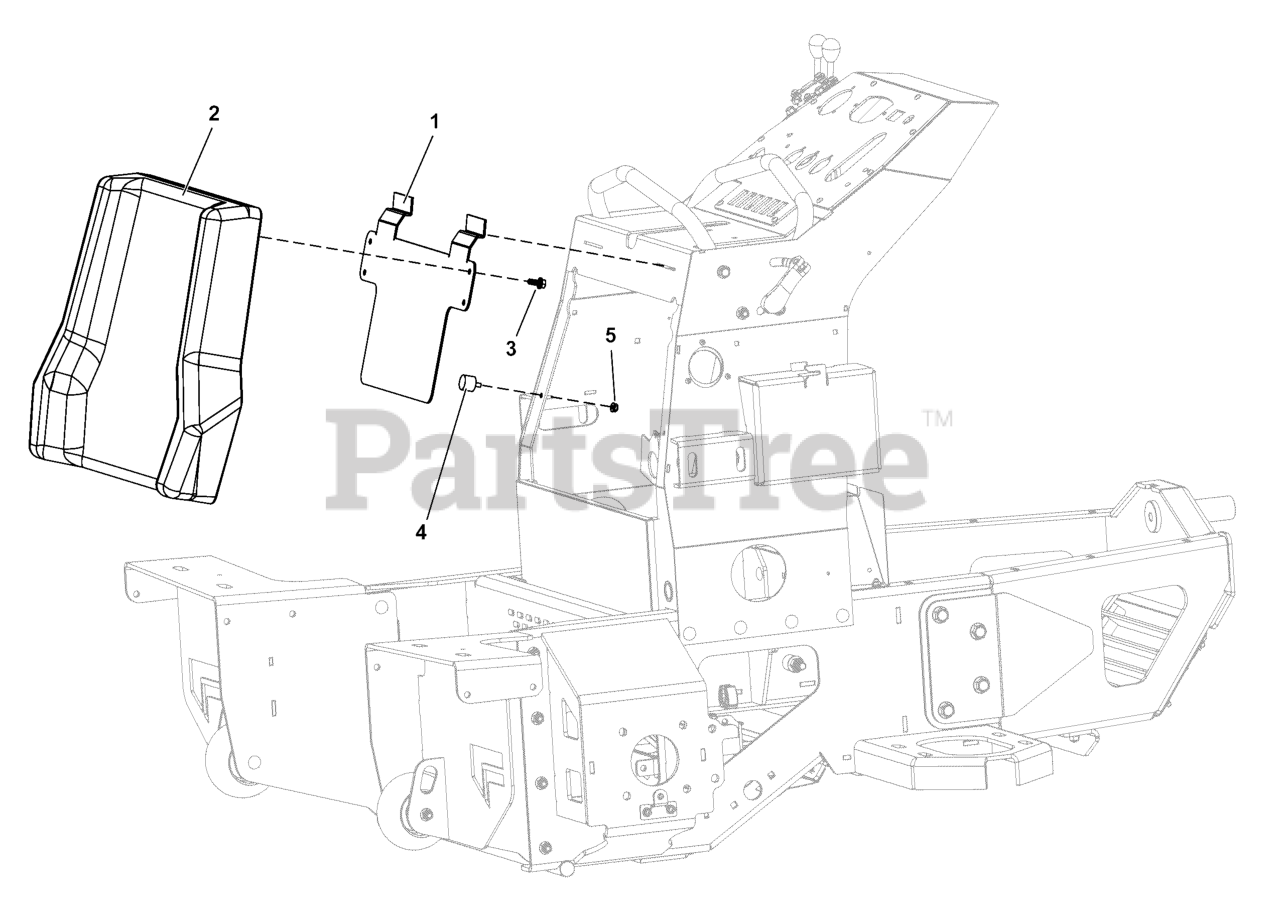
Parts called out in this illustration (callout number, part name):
1	BRKT, THIGH PAD REMOVEABLE
2	KNEE PAD, STAND ON
3	SCR-CAP, HSWH .313"-18 X .750" SS188
4	BUMPER, RUBBER, 1/4-20
5	NUT-HEX-NYLK, FLG .250"-20 SS188
